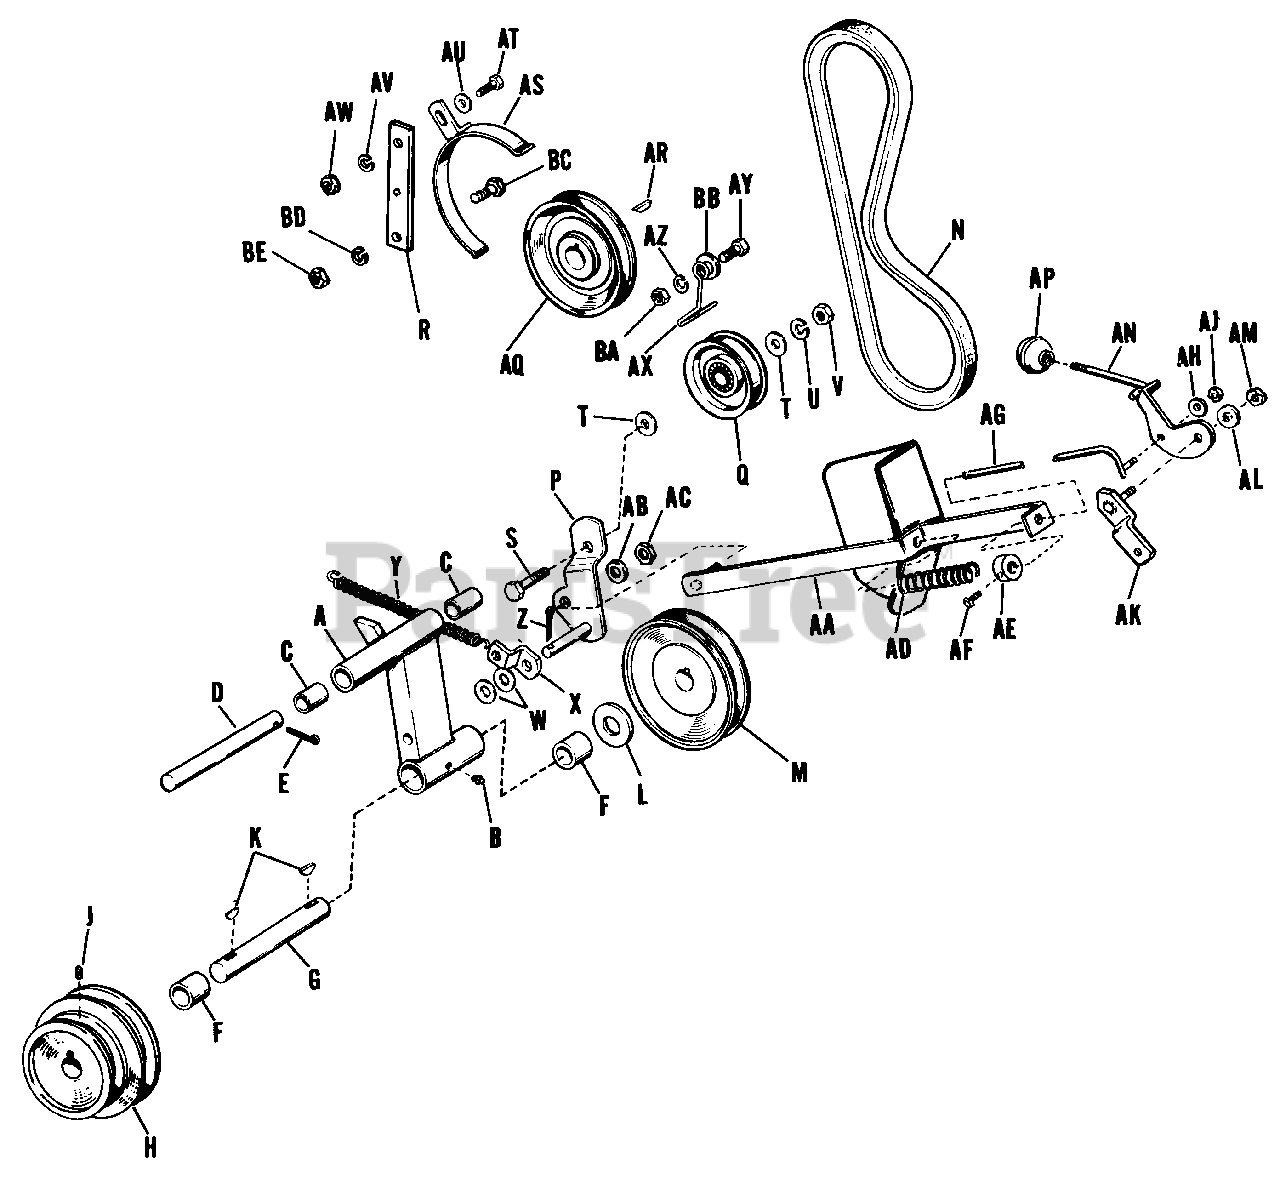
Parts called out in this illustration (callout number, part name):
A	Bracket Assembly, Drive
B	Fitting, Grease
D	Rod, Pivot
E	Pin, Cotter
F	Bearing, Needle
G	Shaft, Power Take-Off
H	Pulley, Power Take-Off
J	Screw, Set, Cup Point, Socket Hd., 5/16"-18 N.C. x 5/16" lg.
K	Key, Woodruff
N	Belt, "V", Power Take-Off
P	Lever Assembly, Idler
Q	Pulley, Idler
R	Guard Support
S	Capscrew, Hex Hd., 3/8"-16 N.C. x 1-1/4" lg.
T	Washer, Plain, 5/16"
U	Washer, Lock, 3/8"
V	Nut, Hex, Full, 3/8"-16 N.C.
W	Washer, Plain, 3/8"
X	Clip, Spring
Y	Spring, Tension
Z	Pin, Cotter, 1/8" x 3/4" lg.
AA	Guide Assembly, Rod
AB	Washer, Plain, 3/8"
AC	Nut, Lock, Hex Hd., Full, 3/8"-16 N.C.
AE	Collar, Set
AF	Screw, Set. Sq. Hd. Cup Pt., 1/4"-20 N.C. x 3/8" lg.
AG	Rod Assembly, Clutch
AH	Washer, Plain, 5/16"
AJ	Nut, Lock, Hex Hd., Full, 5/16"-18 N.C.
AK	Pivot Bar Assembly
AL	Washer, Plain, 3/8"
AM	Nut, Lock, Hex Hd. Full, 3/8"-16 N.C.
AN	Lever Assembly, Clutch
AS	Guard Assembly, Belt
AT	Capscrew, 3/8"-16 N.C. x 1" lg.
AU	Washer, Plain, 3/8"
AV	Washer, Lock, 3/8"
AW	Nut, Hex, Full, 3/8"-16 N.C.
AX	Stop, Belt
AY	Capscrew, 3/8"-16 N.C. x 7/8" lg.
AZ	Washer, Lock, 3/8"
BA	Nut, Full, Hex, 3/8"-16 N.C.
BB	Washer, Plain, 3/8"
BC	Hex Capscrew, 5/16"-18 x 1" lg.
BD	Lockwasher, 5/16"
BE	Hex Nut, 5/16"-18
